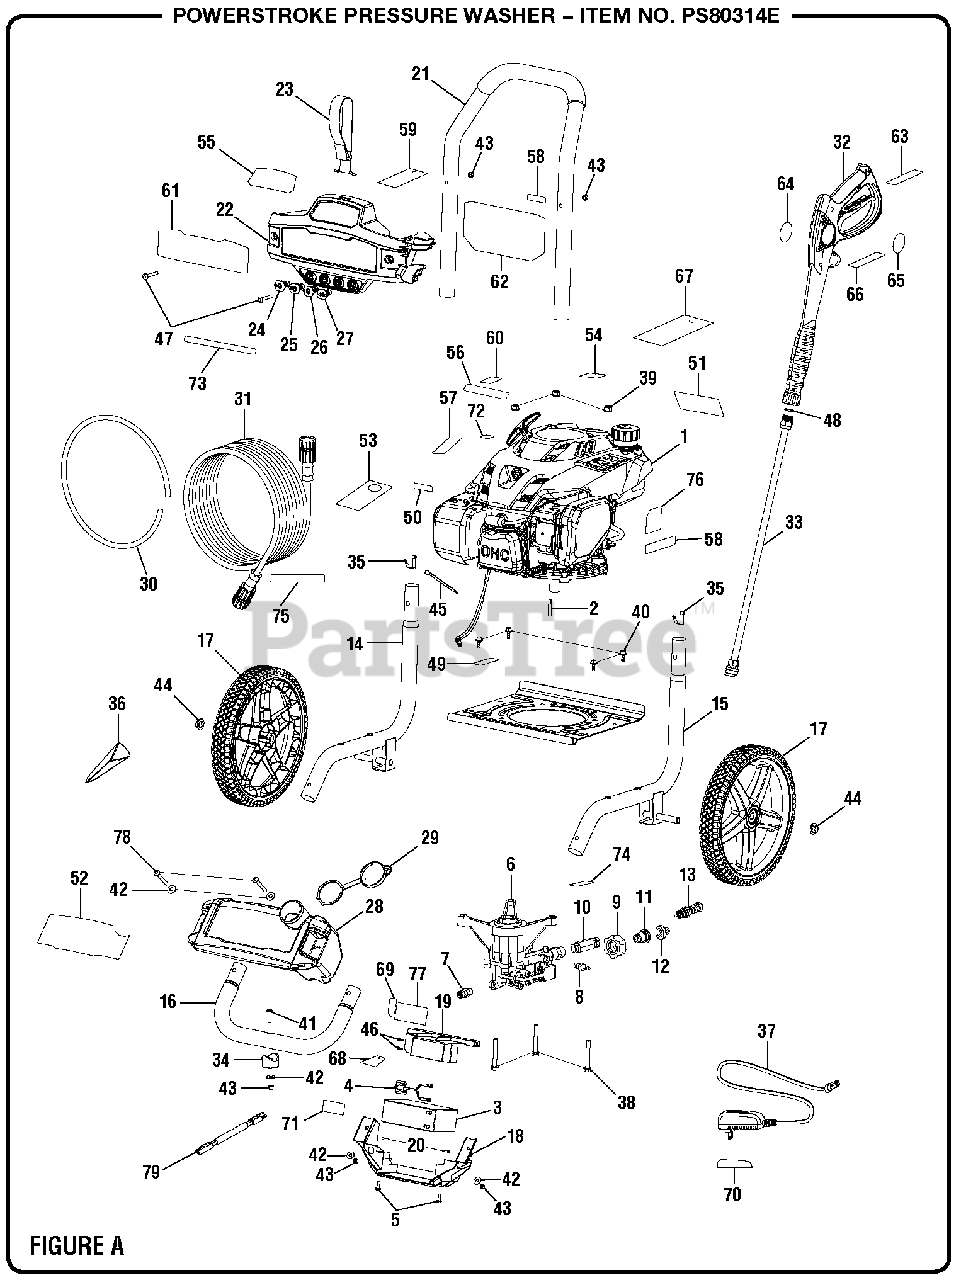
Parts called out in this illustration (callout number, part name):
1	Engine (Subaru EA190)
2	Output Shaft Key
4	Battery and Charger Wire Harness
5	Bolt (M6 x 16 mm, T-30 Torx Pan Hd)
6	Pump
7	Thermal Release Valve
8	Soap Injector Kit
9	Inlet Filter Adapter
10	Outlet Tube
11	Inlet Filter Connector
12	Inlet Filter Screen
13	Unloader Valve Assembly
14	Left Frame Assembly
15	Right Frame Assembly
16	Front Frame Assembly
18	Battery Mount Bracket
19	Battery Hold Down
21	Handle Assembly
22	Hose & Nozzle Holder Assembly
23	Hose Holder Strap
24	15deg Deg Nozzle
25	25deg Deg Nozzle
26	40deg Deg Nozzle
27	Soap Nozzle
28	Soap Tank
29	Soap Tank Cap
30	Chemical Siphon Tube
31	Hose (30 ft.)
32	Trigger Handle Assembly
33	Wand Assembly
35	Handle Spring Clip
37	Battery Charger
38	Bolt (M8 x 60 mm, Flange Hex Hd.)
39	Flange Lock Nut (M8)
40	Flange Bolt (M6 x 16 mm)
41	Bolt (M6 x 48 mm, T-30 Torx Hd.)
42	Washer (1/4 in.)
43	Lock Nut (M6)
44	Wheel Cap
46	Screw (M4 x 12 mm, T-20 Torx Hd.)
47	Bolt (M6 x 42 mm, T-30 Torx Pan Hd.)
49	Combustion Warning Label
50	Choke Label
51	Danger Label
52	Detergent Tank Label
53	Oil Dipstick Hang Tag
54	E85 Label
55	Electric Start Label
56	Subaru Label
57	Hot Surface Label
58	Inquiries Label
59	Standard Nozzle Hangtag
60	Start Label
61	Performance Label
62	Quick Start Label
63	Trigger Handle Warning Label (French/Spanish)
64	Trigger Wand Logo Label
65	Trigger Handle Warning Label (En)
66	Trigger Handle Spec Label
67	Danger Hang Tag
68	Battery Cordwrap Label
69	Battery Bracket Label
70	Battery Maintainer Label
71	Battery Replacement Label
72	Add Oil Label
73	Nozzle Selection Label
74	Hose Outlet Label
75	Hose Hangtag
76	Fuel Valve Label
77	Charge Warning Label
78	Bolt (M6 x 50 mm, T-30 Torx Pan Hd.)
79	Wiring Harness
